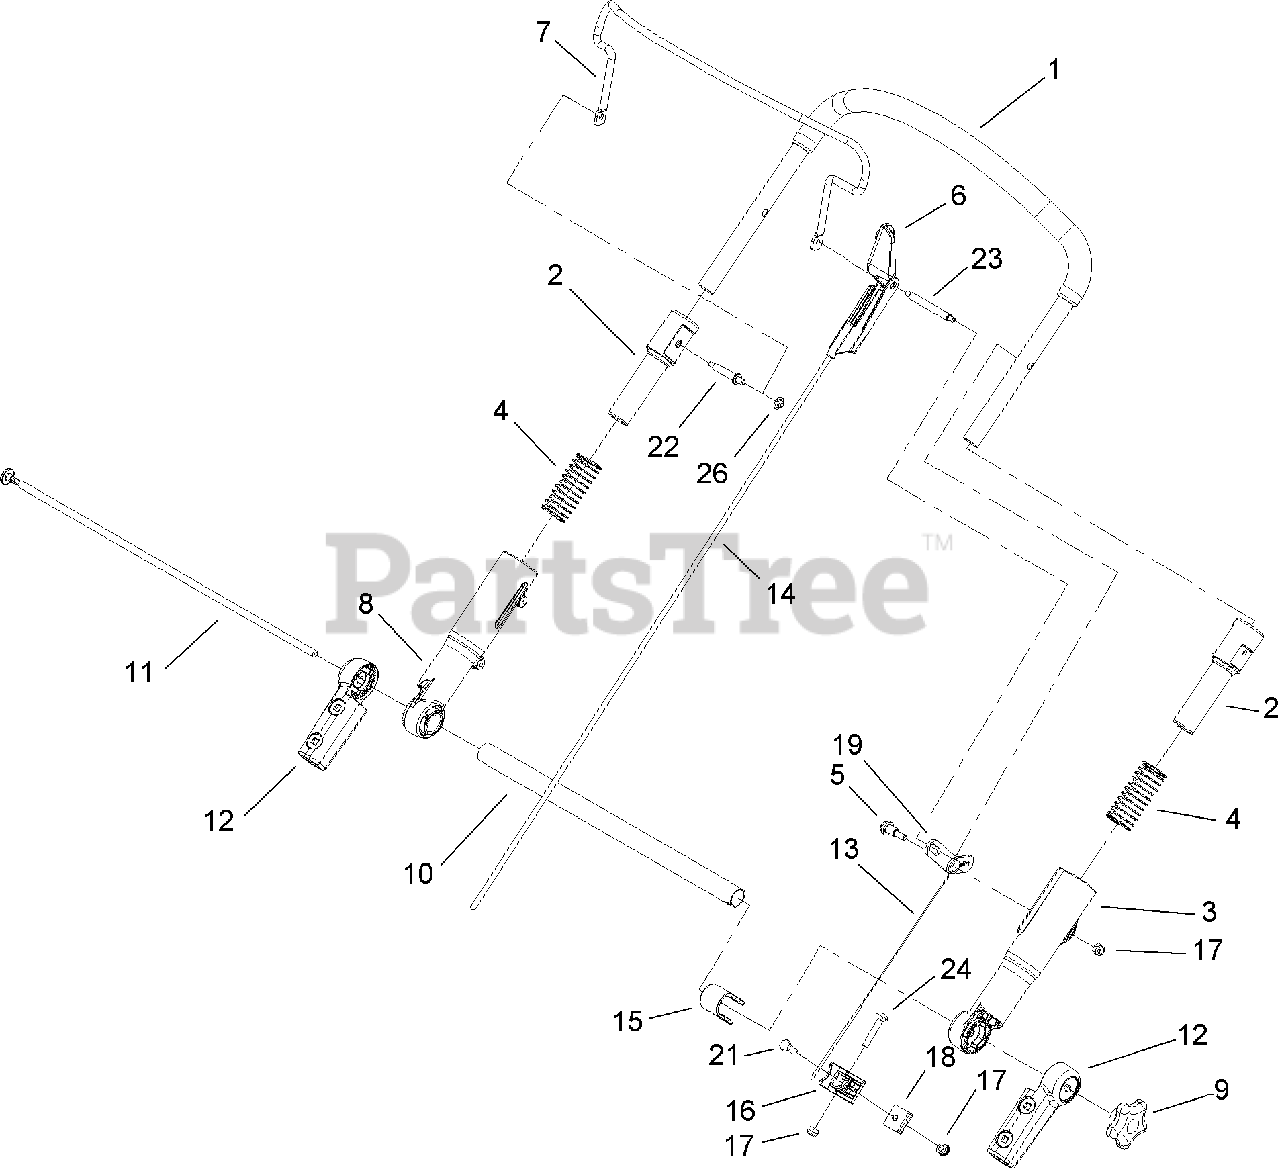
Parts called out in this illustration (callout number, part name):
1	UPPER HANDLE ASM
2	SLEEVE-INNER
3	SLEEVE-OUTER, LH
4	SPRING-COMPRESSION
5	BOLT-SHOULDER
6	STOP-PIVOT
8	SLEEVE-OUTER, RH
11	ROD-THREADED
12	MOUNT-HANDLE, LOWER
13	CABLE-TRACTION
14	CABLE-BRAKE
15	SUPPORT-CABLE
16	SUPPORT-GUIDE, CABLE
17	NUT-LOCK, NI
18	CLAMP-CABLE
19	LEVER-TRACTION
21	SCREW-HH
22	PIN-HANDLE
23	PIN-BAIL, LH
24	SCREW-CARR
26	RETAINER-PUSH ON
